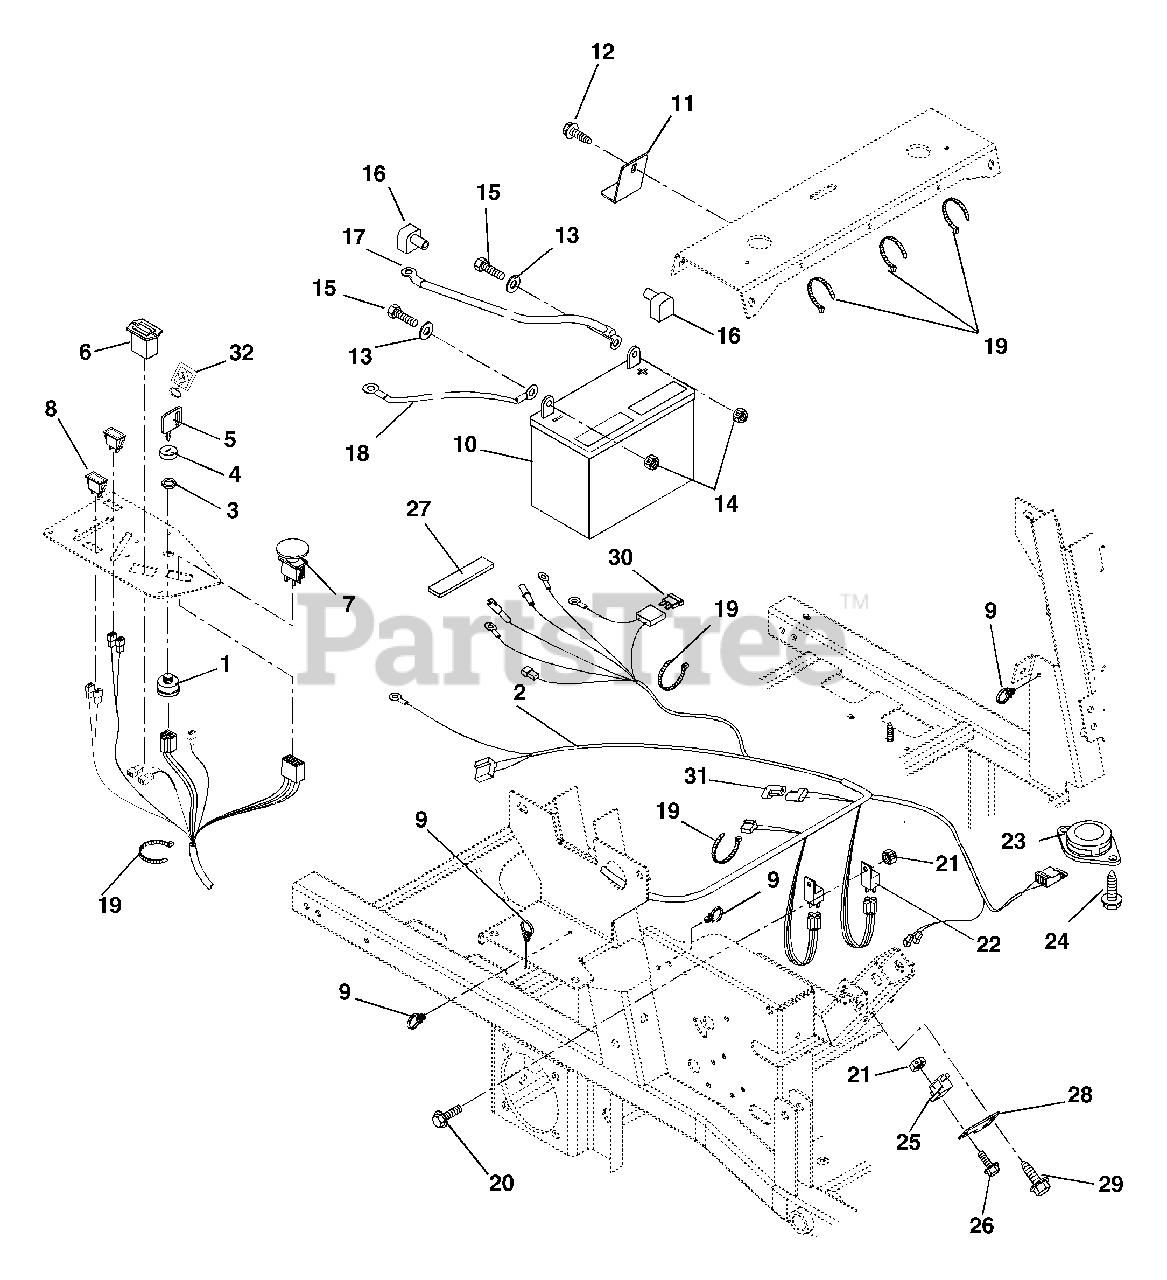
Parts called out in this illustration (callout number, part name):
1	Key Switch (029, 030, 032, 033, 034, 035)
1	Key Switch (020)
2	Harness, Z 6-Pin Wiring (020, 029, 030, 034, 035)
2	Harness, Wiring-EFI (032, 033)
3	Nut-Panel .562-24
4	Cap-Ignition Switch
5	Key-with Cap
6	Hour Meter
7	Switch-Clutch With Retainer Ring
8	Light-Indicator Kit (020, 029, 030, 034, 035)
8	Light-Indicator Kit (032, 033)
9	Tube Clip .75 (020, 029, 030, 034, 035)
9	Tube Clip 1 1/2 (032, 033)
10	Battery with Tube
11	Clamp-Battery Hold Down
12	Screw-Tapping .25-20 x .50 Hex Washer Head
13	Washer-Flat-Steel .281 x .620 x .065
14	Nut-Locking-Center .25-20
15	Bolt-Hex .25-20 x .75 Grade 5
16	Insulator
17	Positive Cable 22"
18	Ground Cable
19	Cable Tie
20	Screw-Machine 10-24 x .50 Hex Washer Head (020, 029, 030, 034, 035)
20	Screw-Machine 10-24 x .50 Hex Washer Head (032, 033)
21	Nut-Locking-Nylon 10-24 With Insert
22	Relay
23	Seat Switch
24	Screw-Tapping 12-24 x .50 Hex Washer Head
25	Switch-Single Pole
26	Screw-Machine 10-24 x .75 Hex Washer Head
27	Pad-Battery
28	Plate-Switch
29	Screw-Tapping .38-16 x .50 Hex Washer Head
30	Fuse, 30 Amp
31	Molded Diode Plug-Black 1-Amp
32	Key Chain
